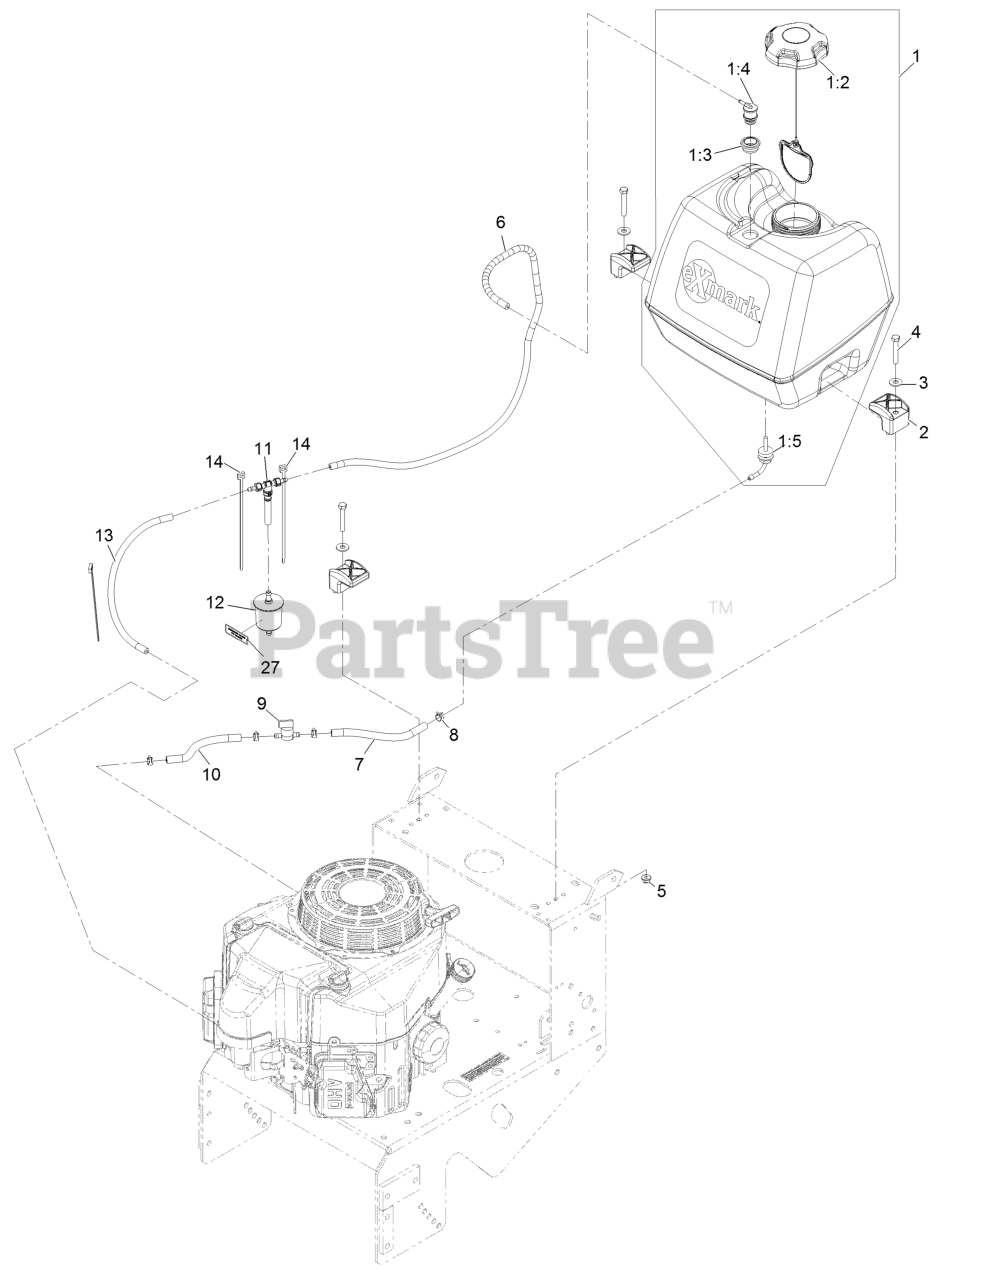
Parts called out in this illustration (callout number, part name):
1	ASM, FUEL TANK
1:3	GROMMET
1:4	VALVE-VENT, FUEL
1:5	FITTING-FUEL, BULKHEAD
3	WASHER-FLAT
4	SCREW-HH
5	NUT-HF, NI
6	HOSE-EMISSIONS
7	HOSE-FUEL
8	CLAMP-HOSE
9	VALVE-FUEL
10	HOSE-FUEL
11	TEE AND CHECK
12	FILTER-FUEL
13	HOSE-FUEL
14	TIE-PLASTIC
27	DECAL-FILTER, EMISSIONS
